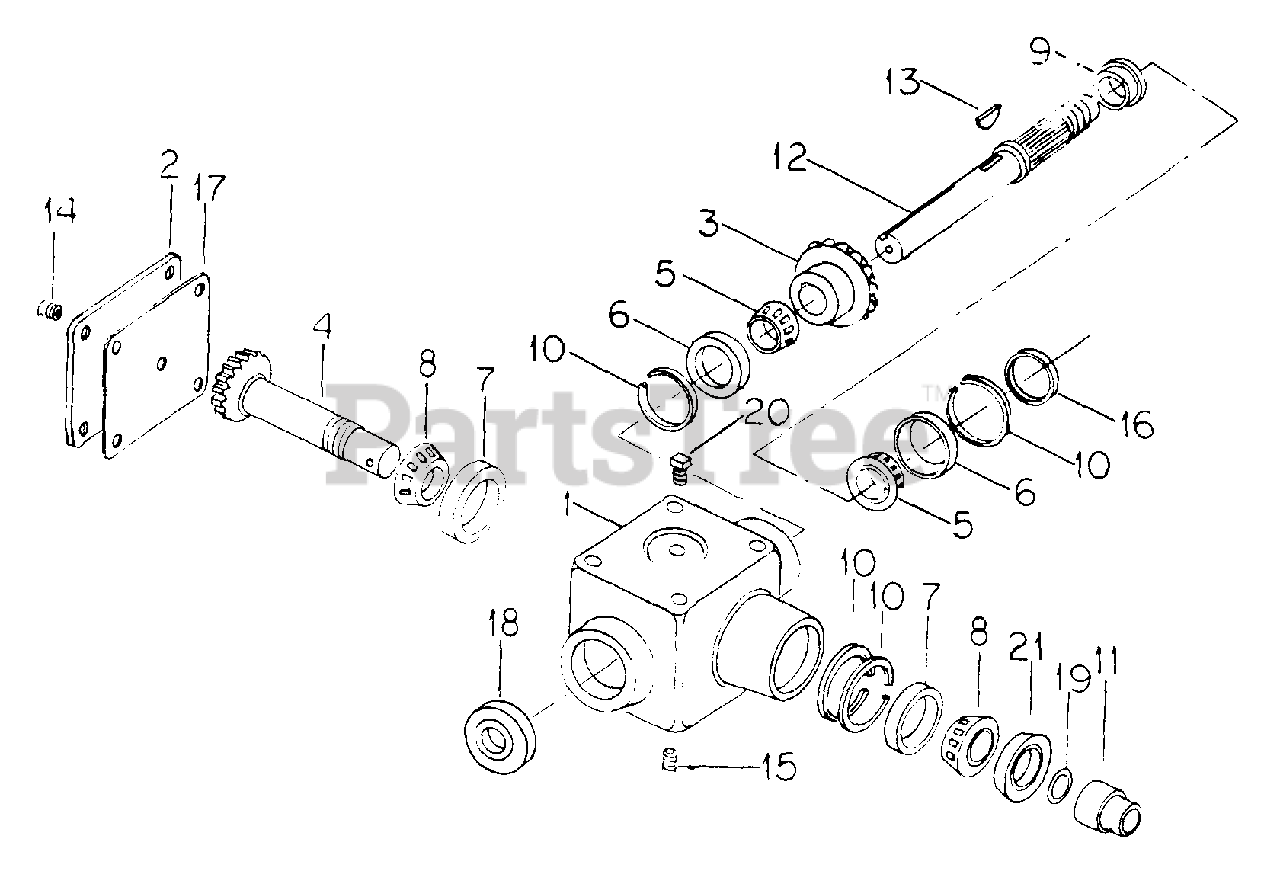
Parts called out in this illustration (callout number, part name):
1	HOUSING, GEAR BOX
2	COVER
4	SHAFT, BEVEL PINION
5	BEARING, CONE
6	BEARING, CUP
7	BEARING, CUP
8	BEARING, CONE
9	NUT, STAKE
11	NUT, STAKE
12	SHAFT, OUTPUT
13	KEY, 1/4 x 7/8 SAE WOODRUFF
14	PLUG, 1/8-27 SQ/HD AUTO PIPE
15	PLUG, 3/8-18 HEX/SKT AUTO PIPE
16	CAP
18	SEAL, OIL
19	O-RING, 1-1/8 x 1-5/16 CLASS 5
